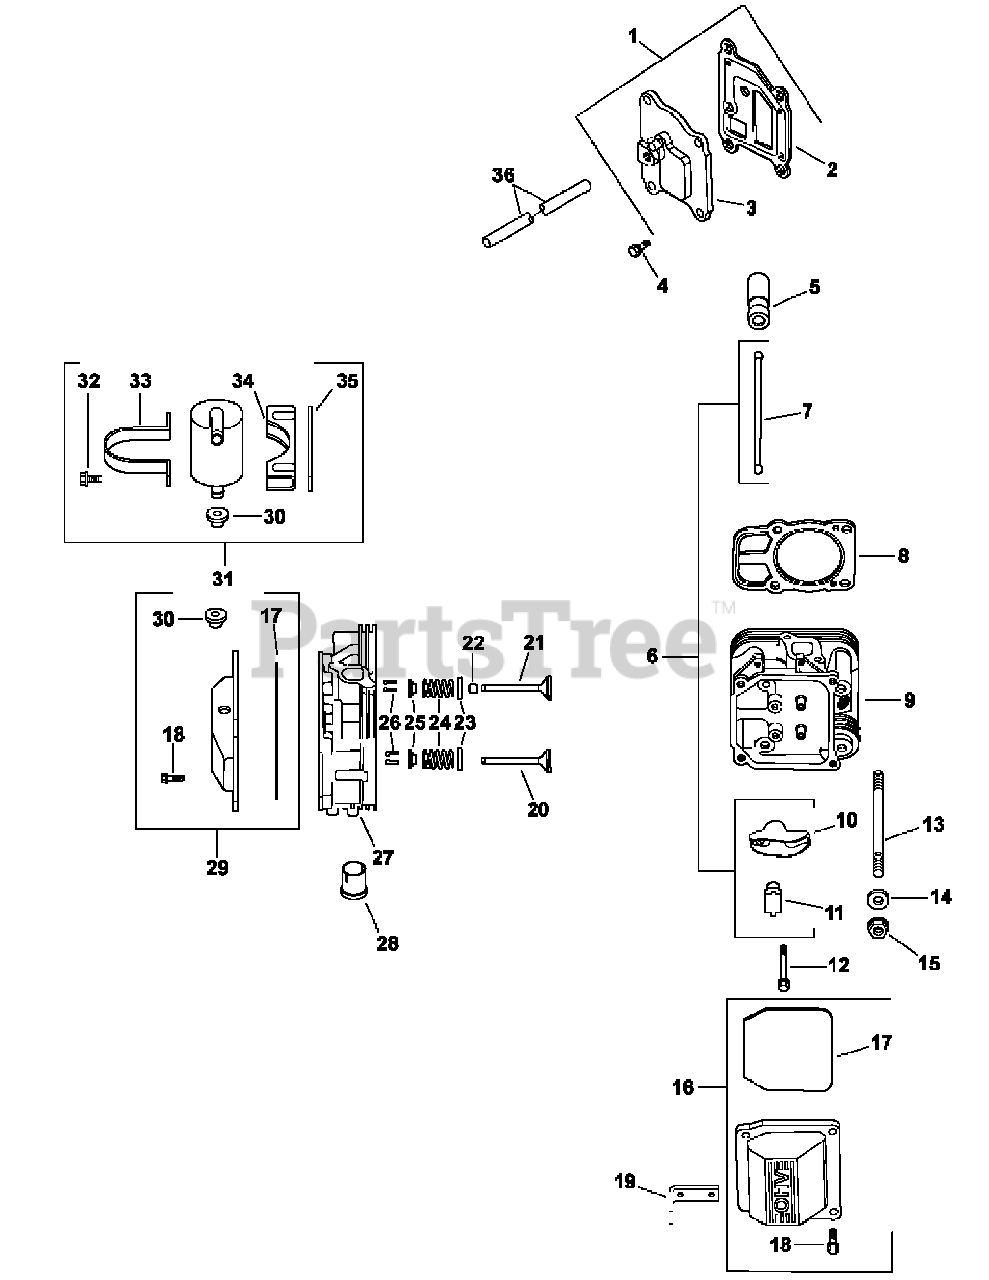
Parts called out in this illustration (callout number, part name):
1	Breather Cover Kit
2	Breather Gasket
3	Breather Cover
4	Hex Flange Screw
5	Valve Lifter
6	Valve Train Kit
9	Head Assembly #2 Cylinder
11	Rocker Arm Pivot
12	Hex Flange Screw
13	Cylinder Head Stud
14	Flat Washer 1/4
15	Hex Flange Nut
16	Valve Cover Kit, Plain
18	Hex Flange Screw
19	Lifting Strap
20	Exhaust Valve (Std.)
20	Exhaust Valve (.25)
21	Intake Valve (Std.)
21	Intake Valve (.25)
22	Valve Stem Seal
23	Spring Retainer
24	Valve Spring
25	Valve Spring Cap
26	Retainer Kit
27	Head Assembly #1 Cylinder
28	Exhaust Port Liner
29	Valve Cover Kit, Breather
30	Rubber Grommet
31	Breather Separator Kit
33	Strap
36	Flexible Hose
